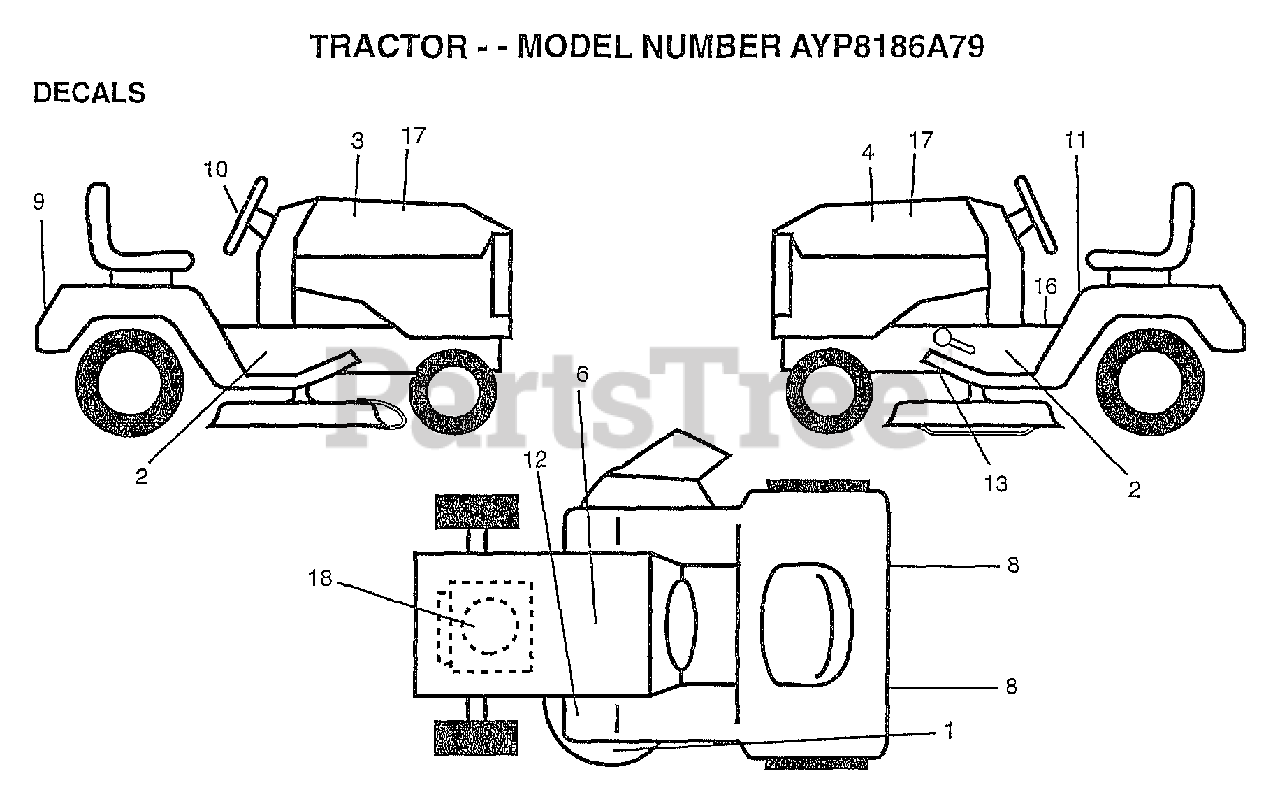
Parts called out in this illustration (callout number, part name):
1	"DECAL DECK,MULCH"
2	"DECAL CHASSIS 46"""
3	DECAL.HD.RH.WIZAR
4	DECAL.HD.LH.WIZAR
6	DECAL.BATRY.3-3908
8	REFLECTOR-TAIL YT
10	DECAL.INS.STRG.WL
11	"DECAL DANGER,FEND"
13	"DECAL.V.BELT.44"""
16	"DECAL DASH,OPER."
17	DECAL INSERT HOOD
18	DECAL, HP, ENGINE
